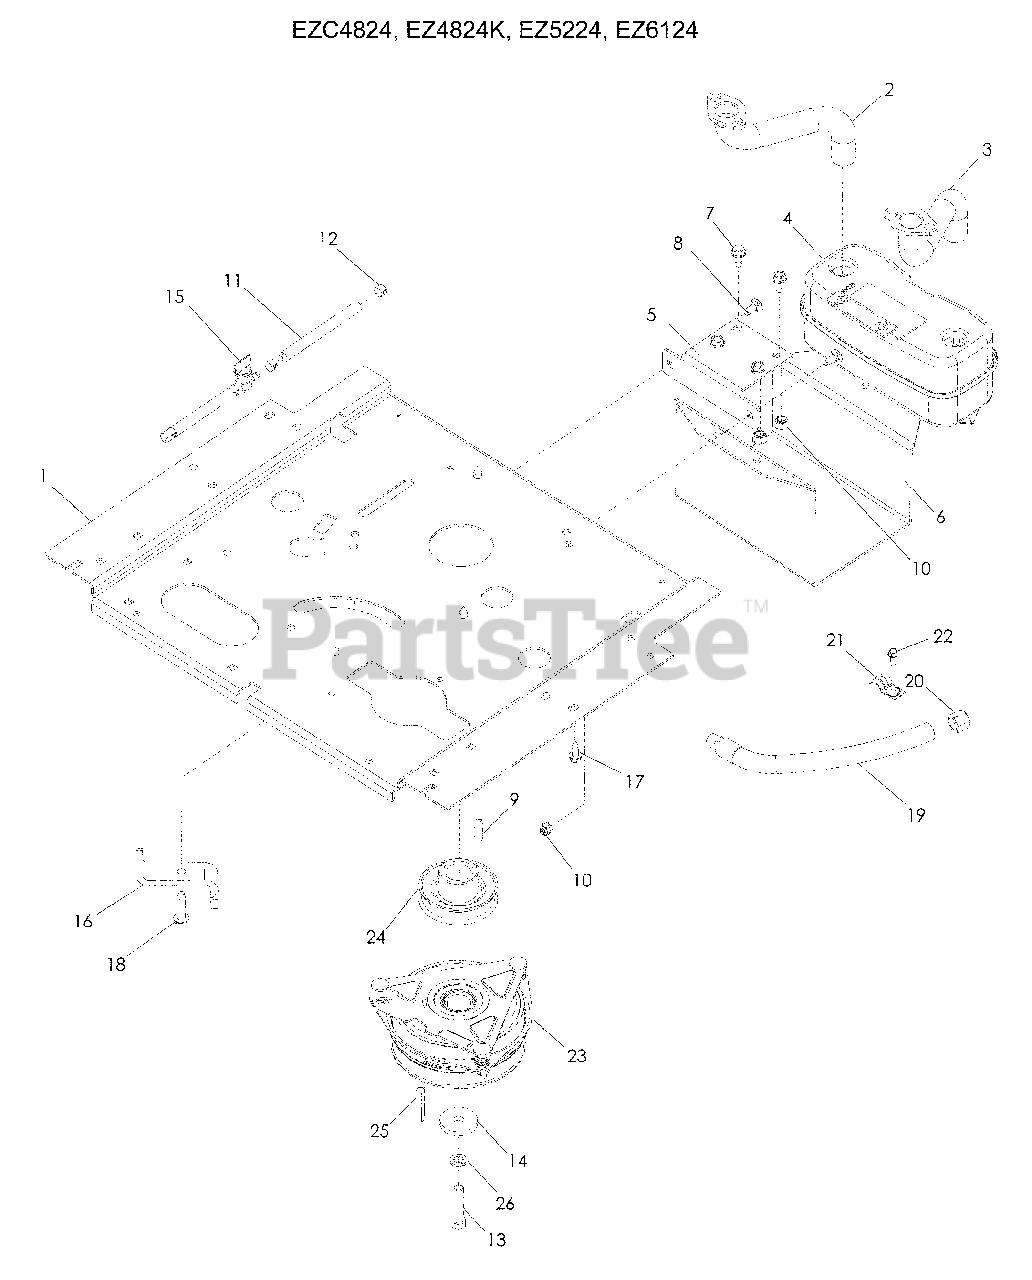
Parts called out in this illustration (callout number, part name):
1	PLATE, ENGINE
2	EXHAUST TUBE, RT
3	EXHAUST TUBE, LT
4	MUFFLER ASM TWIN
5	BRACKET, MUFFLER
6	GUARD, MUFFLER
7	BOLT 5/16-18 x ¾ THD FRM
8	RHSNB 5/16-18 x ¾
9	KEY ¼ SQ x 1
10	NUT 5/16-18 FLANGE NYLOC
11	FUEL LINE 5"
12	CLAMP, HOSE
13	HCS 7/16-20 x 2 GR8
14	WASHER, HEAVY
15	VALVE, FUEL
16	STOP, CLUTCH
17	HHFS 3/8-16 x 1 THD FRM
18	BOLT 3/8-16 x 1½ THD FRM
19	HOSE, DRAIN
22	SCREW ¼-20 x 5/8 SLF TAP
23	CLUTCH, 150 FT/LBS
24	PULLEY, DRIVE
25	KEY ¼ SQ x 2
26	WASHER 7/16 SLW
